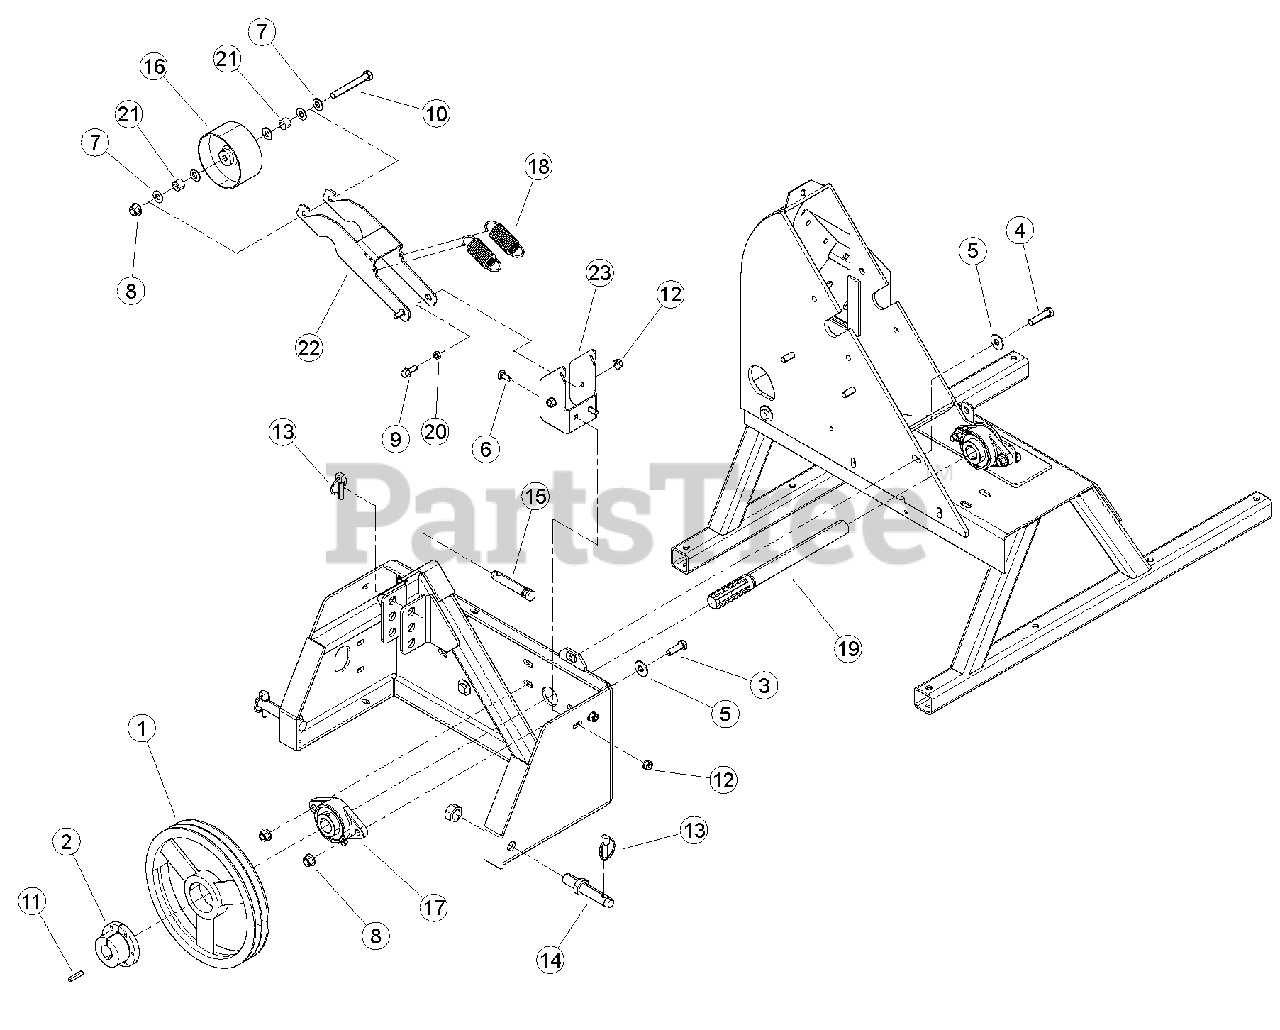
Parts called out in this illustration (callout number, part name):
1	SHEAVE, 2B12.4 SK
2	BUSHING, SK 1-1/4"
3	BOLT, 1/2 X 1-1/2 HEX HD GR5 ZP
4	BOLT, 1/2 X 2 GR5 HEX CAPSCREW ZP
5	WASHER, 1/2" FLAT ZP
6	BOLT, 3/8 X 1" GR5 CRG NC ZP
7	WASHER, 1/2" SAE FLAT ZP
8	NUT, 1/2-13 NYLOCK FLANGE
9	BOLT, 3/8 X 1 FLANGE NC
10	BOLT 1/2 X 4 HEX CPS G5 ZP
11	KEY, 1/4 SQ X 1-1/2 LG PLAIN
12	NUT, 3/8-16 NYLOCK FLANGE
13	PIN, 7/16 X 1-3/4 LYNCH
14	PIN, LIFT ARM 7/8 X 5" LG
15	PIN, TOP LINK 3/4 X 4-1/2"LG
16	PULLEY, IDLER 5 X 2.50"
17	BEARING, 1-1/4" DIA 2 BOLT FLANGE
18	SPRING, 1.25 OD X 3.50 LG X .148 WD
19	SHAFT, 6 SPLINE 5" CHIPPER
20	SPACER, IDLER PIVOT
21	SPACER, .81 X .620
22	ARM, INSIDE IDLER
23	BRACKET, INSIDE IDLER ARM MOUNTING
